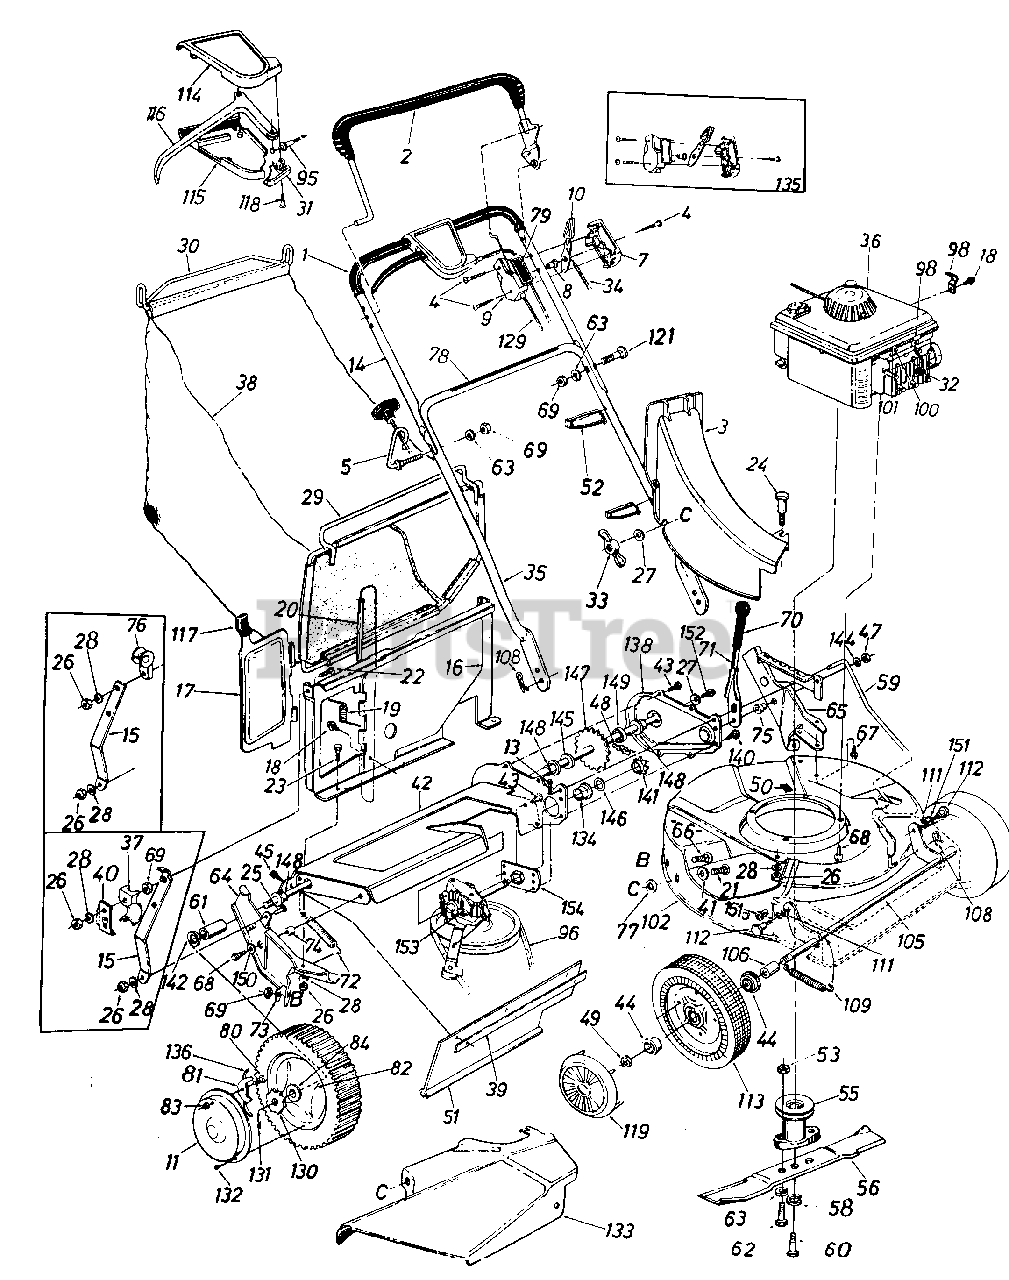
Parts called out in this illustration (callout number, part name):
1	GRIP-SHRINK-25 IN
3	CHUTE ASSY-TOP DISCH
4	SCREW-TRUSS MACH
5	SCREW-RECOIL HANDLE GUIDE
7	PANEL HALF-CONTROL
8	PIN-CONTROL DISC
9	PANEL HALF-CLUTCH
10	LEVER-THROTTLE CONT-REV
11	HUB CAP
13	PIN-COTTER-3/32 DIA X .75
14	HANDLE-UPPER-CHROME
15	BRACKET-PANEL SUP
16	PANEL ASSY-CATCHER
17	DOOR-TOP DISCHARGE
18	SCREW-HEX B-TAP #10 X .38
19	SPRING-TORSION
21	BOLT-CARRIAGE 1/4-20 X .62
22	SCREW-TRUSS MACH
23	SCREW-HEX 1/4-20 X .50
24	SCREW-SHLD
25	SCREW-HEX 1/4-20 C .62
26	NUT-HEX 1/4-20
27	WASHER-SPRING BELL
28	LOCK WASHER 1/4 DIA
29	FRAME-FRONT
30	ROD-HGT ADJ
31	CAP-CABLE MTG
32	INSULATOR-SPARK PLUG
33	NUT-INS WING L-1/4-20
34	WIRE-THROTTLE 58 LG
35	HANDLE-LOWER PAINTED
37	GUIDE-ROPE
38	BAG-GRASS-CONV
39	STRIP-RETAINING
40	CLIP-SPRING RETAINER
41	WASHER-FL-.344 ID X .62 OD X .033
42	AXLE ASSY-CHAIN
43	SCREW-HEX B-TAP 1/4 X .38
44	BEARING-BALL
45	SCREW-HEX WASH HD
47	NUT-HEX LOCK 3/8-24
48	#48 CHAIN 1/2 PITCH
49	NUT-HEX INS L-1/2-20
51	FLAP-RR
52	TIE-CABLE
53	NUT-5/16-24
55	PULLEY ASSY-BLADE ADAPTER
56	BLADE-21IN
58	WASHER-BELL .390 ID X 1.375 X .062
59	ROD-HGT ADJ 1.50 X 19.42
60	SCREW-HEX 3/8-24 X 2.25
61	SPACER-.513 ID X .703 OD X .69
62	SCREW-HEX SPECIAL 5/16-24X1.0
63	WASHER-LOCK-5/16
64	BRACKET ASSY-HDLE-RH
65	BRACKET ASSY-HDLE-LH
66	BOLT-CARRIAGE 5/16-18 X .62
67	SCREW-HEX WASH HD 5/16-18X1/2
68	SCREW-HEX
69	NUT-HEX 5/16-18
71	LEVER-HGT ADJ
72	SPRING-EXTENSION
73	WASHER-BELL .337 X .867 X .057
75	SPACER-SHLD .500 X .100
76	GUIDE-ROPE
77	RETAINER-BOLT 1/4X.50 OD
80	SCREW-SHLD .342 DIA X .268
81	PAWL
82	WHEEL ASSY W/TIRE-T-TREAD
83	NUT-INS LOCK 1/4-20
84	BEARING-BALL
95	CABLE-CLUTCH X 50.0
96	BELT-V 3/8 X 31.0
98	CLAMP-CASING
100	SCREW-HEX WASH HD TAP
101	CLAMP-CASING
108	PIN-INTERN COT-5/16 DIA
109	SPRING-EXTENSION
111	WASHER-INTERN L 3/8 X.56 OD X .018
112	SCREW-SHLD
113	WHEEL ASSY W/TIRE
114	COVER-HALF-CONTROL
115	COVER-HALF CONT-LWR
116	LEVER-CONTROL
118	SCREW-FL C-SUNK AB
119	HUB CAP-BLACK
121	BOLT-CARRIAGE-CURV 5/16-18 X 1.38
129	CABLE-CONTROL
130	RATCHET
131	PIN-COTTER-1/8 DIA X 1.00
132	SCREW-PAN HD TAPP
133	DEFLECTOR ASSY
134	BUSHING-FL
135	KIT-THROTTLE CONTROL
136	SPRING-NYLON
138	COVER-CHAIN
140	SCREW-HEX WASH SF TAPP
141	SPROCKET-7T
142	WASHER-FL
144	WASHER-FL-.385 ID X .87 OD X .06
145	WASHER-FL
146	WASHER-FL
147	SHAFT ASSY-REAR
148	BEARING-HEX FLANGE .506 ID
149	WASHER-FL-.531 X .930 OD X .050
150	WASHER-FL-.531 ID X 1.25 OD X 1.00
151	BEARING-NYLINER
152	SCREW-1/4-20 X .62
153	TRANSMISSION-COMP
154	BEARING-CUP HEX
